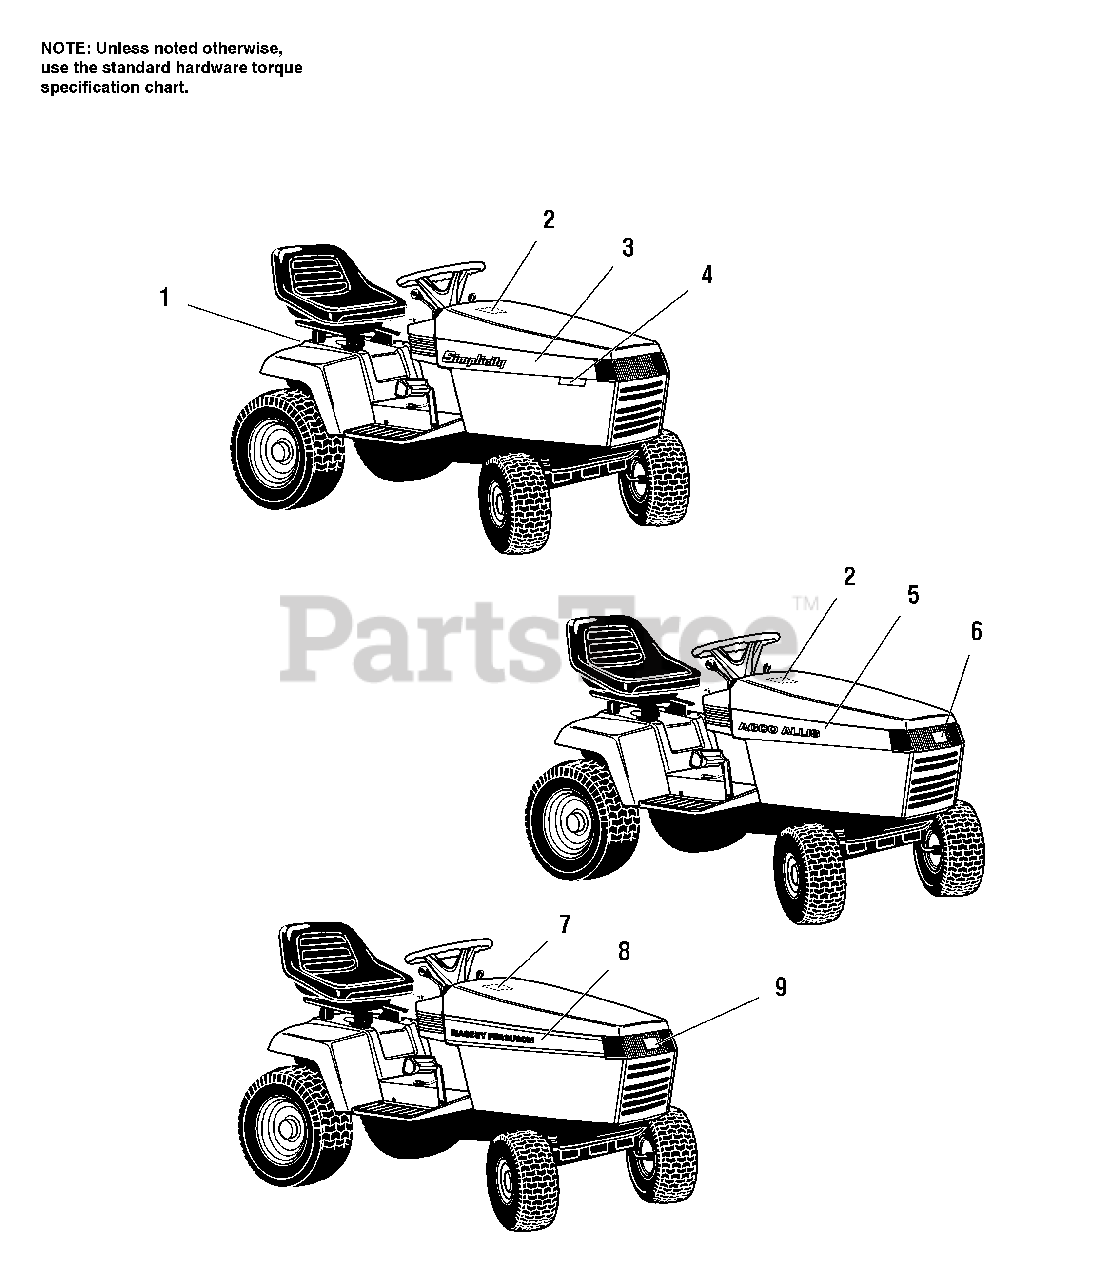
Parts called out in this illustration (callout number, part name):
1	DECAL, Simplicity Logo
2	DECAL, Paint
3	DECAL, RH Hood, Simplicity Broadmoor
3	DECAL, LH Hood, Simplicity Broadmoor
4	DECAL, Model, Simplicity Broadmoor - Hydro 14V-Twin
4	DECAL, Model, Simplicity Broadmoor - Hydro 16V-Twin
4	DECAL, Model, Simplicity Broadmoor - Hydro 15
5	DECAL, LH Hood - AGCO-Allis 1616H
5	DECAL, RH Hood - AGCO-Allis 1616H
5	DECAL, RH Hood - AGCO-Allis 1614VH
5	DECAL, LH Hood - AGCO-Allis 1614VH
5	DECAL, RH Hood - AGCO-Allis 1615H
5	DECAL, LH Hood - AGCO-Allis 1615H
6	DECAL, AGCO Allis Logo
7	DECAL, Paint
8	DECAL, LH Hood, Massey Ferguson 2616H
8	DECAL, RH Hood, Massey Ferguson 2616H
8	DECAL, LH Hood, Massey Ferguson 2615H
8	DECAL, RH Hood, Massey Ferguson 2615H
9	DECAL, Massey Ferguson Logo
